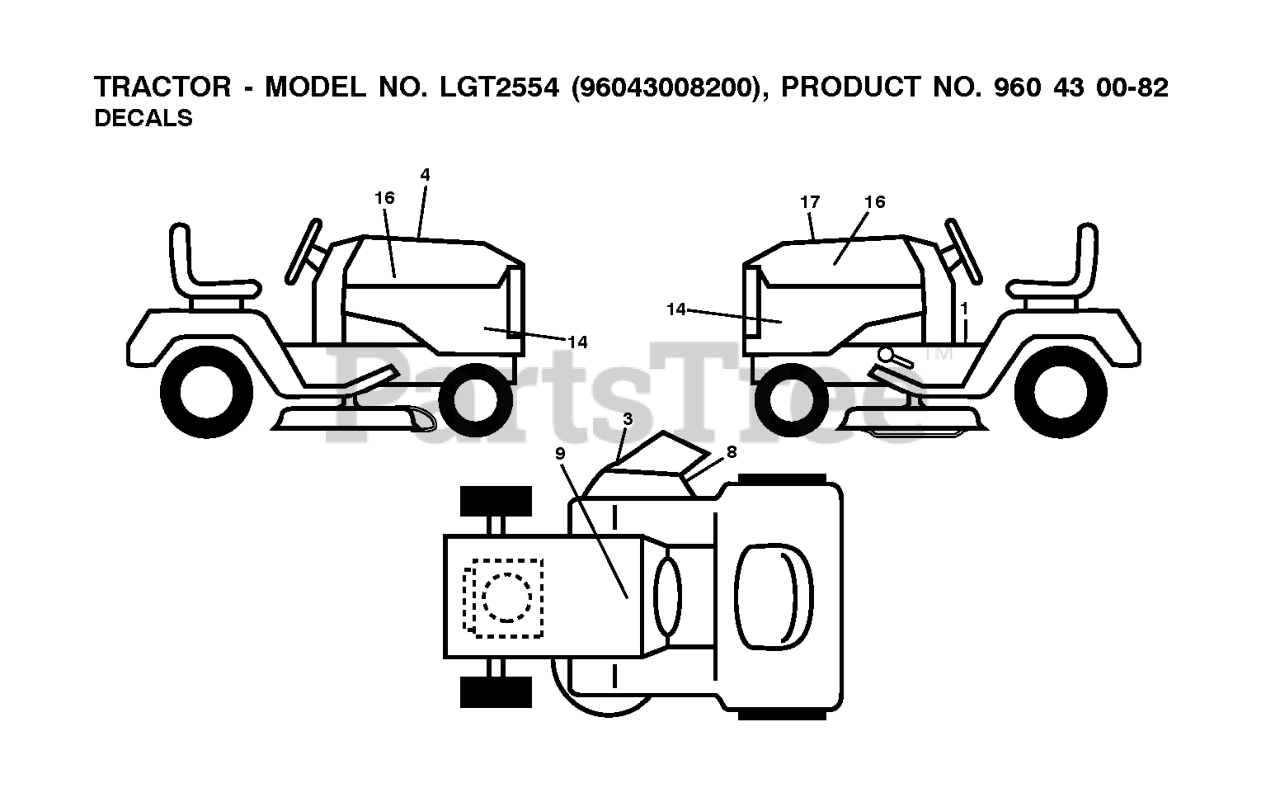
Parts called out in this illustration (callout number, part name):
1	DECAL.FENDER.WARNING.ENG
3	DECAL.WARN.KEEP.HAND.AWAY
4	DECAL.WARNING.CUST.RESP.E85.
8	DECAL.MOWER.SCH.48/54
9	DECAL BTRY SYMBOLS
14	DECAL.PNL.SD.LGT2554.KOHL.
16	DECAL.HOOD.LOGO.ORANGE.HUSQVAR
